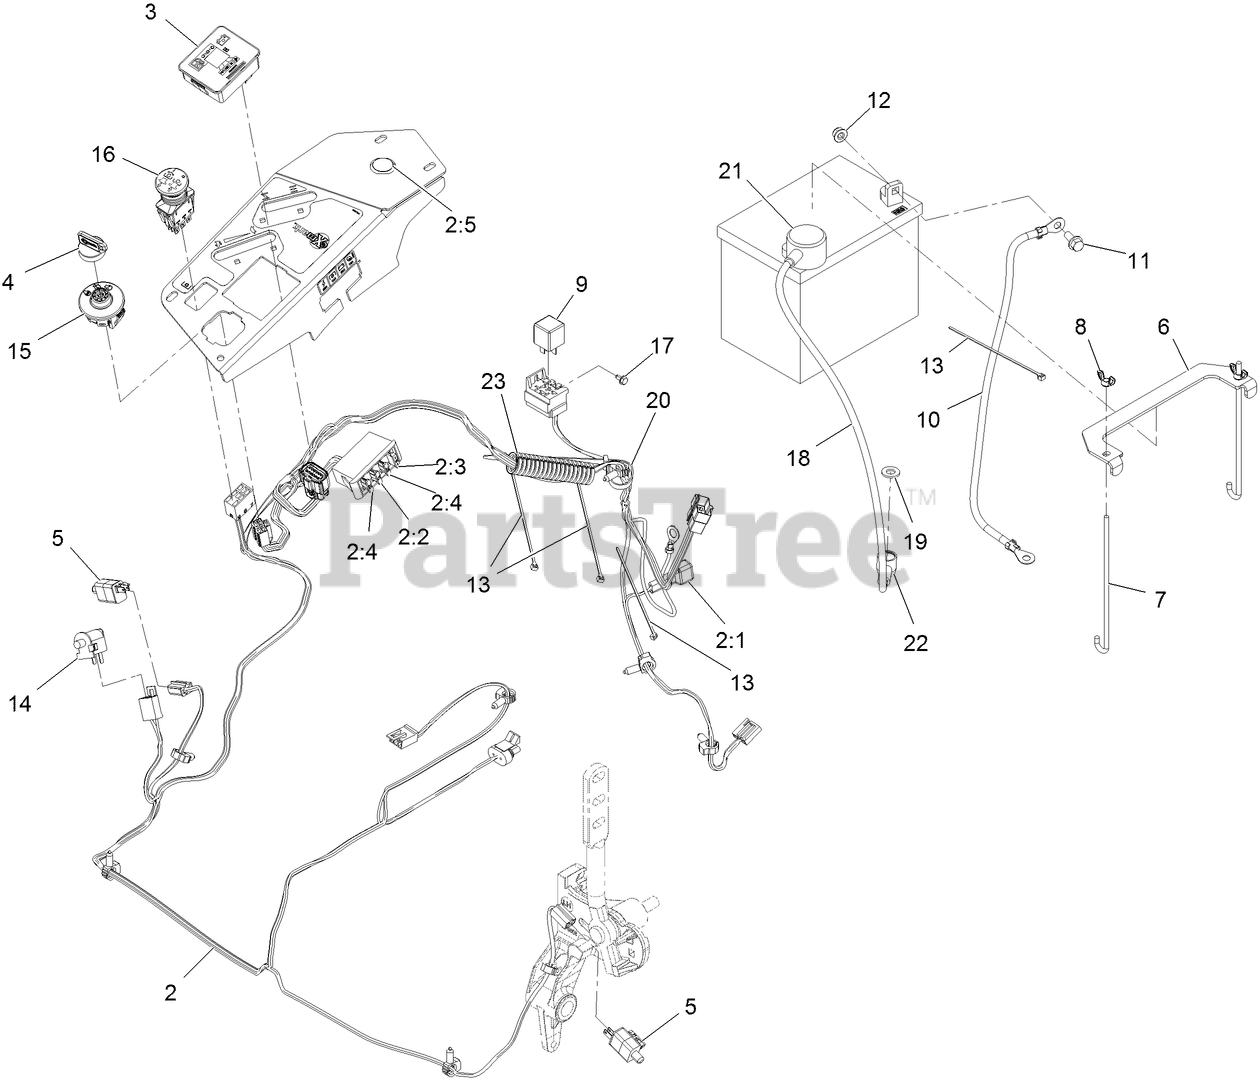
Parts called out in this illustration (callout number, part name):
2	HARNESS-WIRE, MAIN
2:2	FUSE-BLADE, 10 AMP
2:3	FUSE-BLADE, 15 AMP
2:4	FUSE-BLADE, 25 AMP
2:5	CAP-PLUG
3	FUEL/HOUR METER ASM
4	KEYS-IGNITION (SPARE PAIR
4	KEY-IGNITION
6	STRAP-TIE DOWN, BATTERY
7	BOLT-HOLDDOWN
8	WINGNUT
10	CABLE-BATTERY, NEGATIVE
11	SCREW-HHF
12	NUT-HF, NI
13	TIE-CABLE
14	SWITCH-BAIL
15	SWITCH-IGNITION
16	SWITCH, PTO 10A
17	SCREW-HWH
18	CABLE-BATTERY, POSITIVE
19	WASHER-FLAT
20	TIE-CABLE
21	INSULATOR-BATTERY
22	INSULATOR-SOLENOID
23	COVER-HOSE
